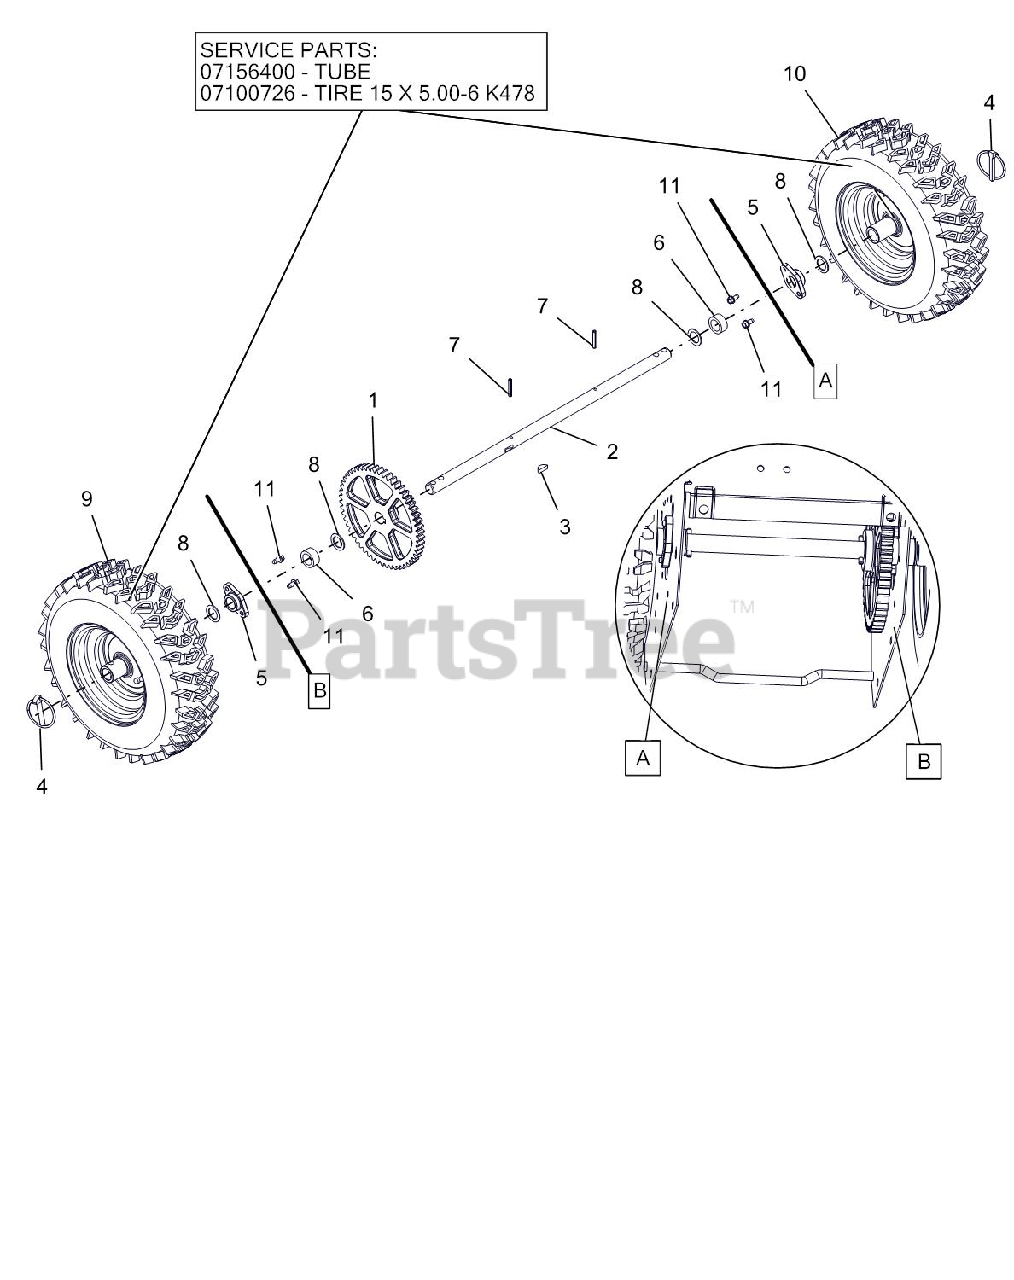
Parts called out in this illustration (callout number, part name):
1	SPUR GEAR, 54T .75ID X 6.75PD
2	SHAFT, AXLE
3	KEY-WDRF .25X.750X.313 SAE91
4	PIN-LOK .31X1.75
5	BSHG .75X1.125X.65
6	BSHG-SLV .766 X 1.125 X .500
7	PIN-ROLL .188X1.25
8	WSHR-FL-STL.754X1.125X.062YWZC
9	TIRE/WHEEL-RH 13X4.00-6 PIN T2
10	TIRE/WHEEL-LH 13X4.00-6 PIN T2
11	SCR-TAP .25-20X.50 HWH TR YWZ
12	TUBE 15 X 5.00-6
13	TIRE, 15X5.00-6 K478
